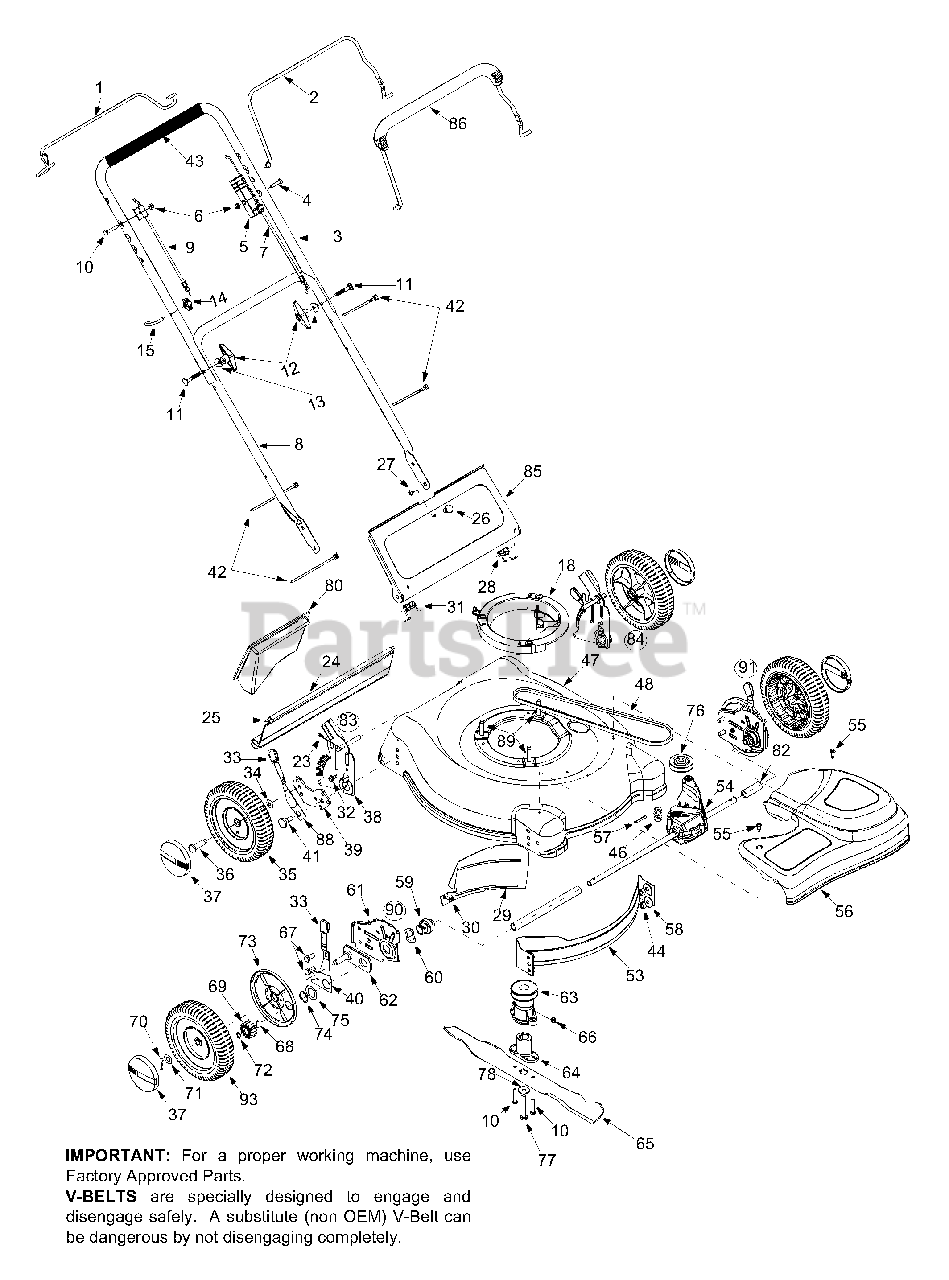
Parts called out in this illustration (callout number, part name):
5	Control Housing
6	Hex Lock Nut 1/4-20
7	Control Cable: 43"
9	Drive Cable
10	Hex Screw 1/4-20 x 1.5"
11	Carriage Bolt
12	Handle Knob
13	Saddle Washer
14	Wing Nut
15	Rope Guide
18	Engine Spacer Assembly
23	Hairpin Clip
24	Rear Trail Shield
25	Wire: Trail Shield
27	Scr. Tr. Mach. #10-24 x 0.380"
28	Torsion Spring LH
30	Scr. AB 1/4-14 x 0.625"
31	Torsion Spring RH
32	Hex Scr. w/ Wash. 1/4-14 x 0.62"
33	Knob
34	Bell Washer .375 x .870
35	Rear Wheel: Disk Bar Gray
36	Shoulder Screw
37	Hubcap: Euro Gray
38	Handle Bracket Assembly LH
39	Pivot Bar LH
40	Front Lever RH
41	Shoulder Screw
42	Cable Tie
43	Foam grip (2 required)
44	Hex Nut
46	Belt Tension Spring
55	Screw #12 x 0.457"
56	Front Drive Cover: Yellow
57	Roll Pin
58	Bell Washer
59	Bearing Support
60	Wave Washer
62	Pivot Plate Assembly
63	Drive Pulley
64	Blade Adapter
65	Mulching Blade w/ Star: 21"
66	Hex Lock Nut
67	Hex Screw
68	Dowel Pin
69	Gear 14T RH
70	Hairpin Clip
71	Flat Washer
72	Snap Ring
73	Wheel Dust Cap
74	Snap Ring
75	Washer DD 1.5" O.D.
76	Input Pulley
77	Hex Bolt
78	Bell Washer
82	Slev. Spacer LH
83	Handle Bracket Assembly RH Compl.
84	Handle Bracket Assembly LH Compl.
88	Spring Lever
89	TT Screw
90	Height Adj. Assembly RH Compl.
91	Height Adj. Assembly LH Compl.
93	Wheel, 8x2 x 1.75
